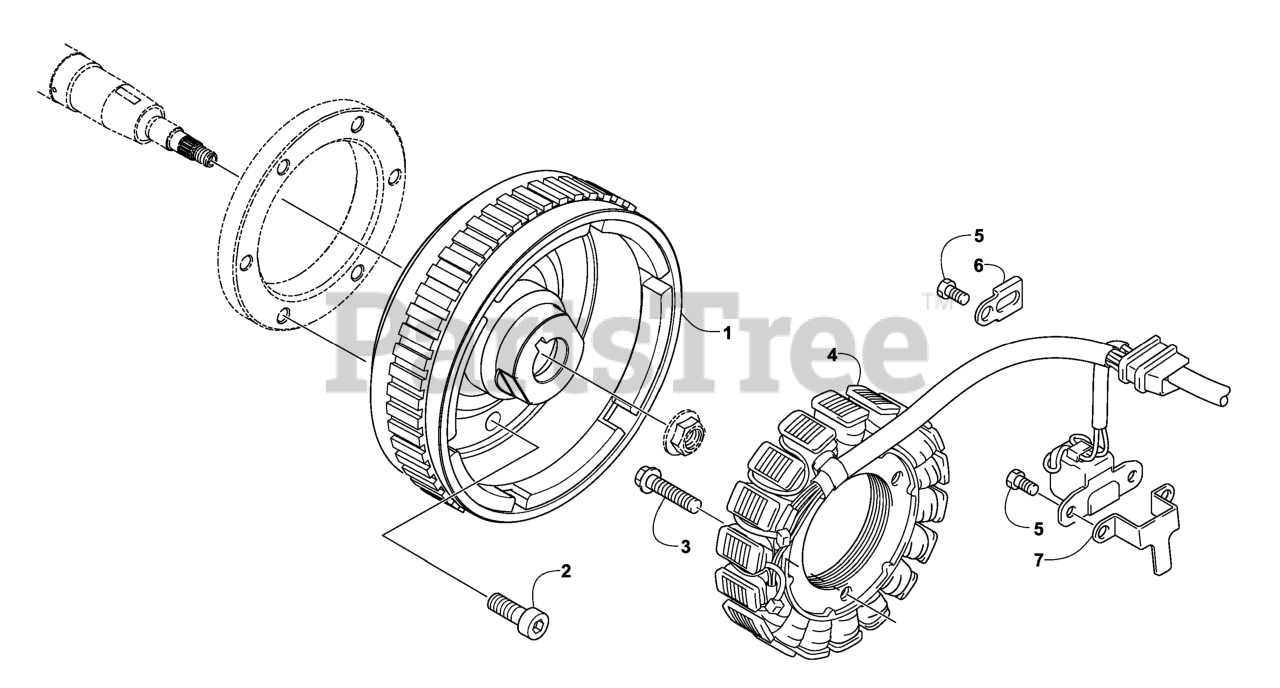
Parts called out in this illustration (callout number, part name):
1	ROTOR-IGNITION, EFI
2	SCREW-HSH
3	BOLT-FLANGE
4	Stator Assembly
5	BOLT-HEX
6	CLAMP-MAGNETO
7	CLAMP-MAGNETO
